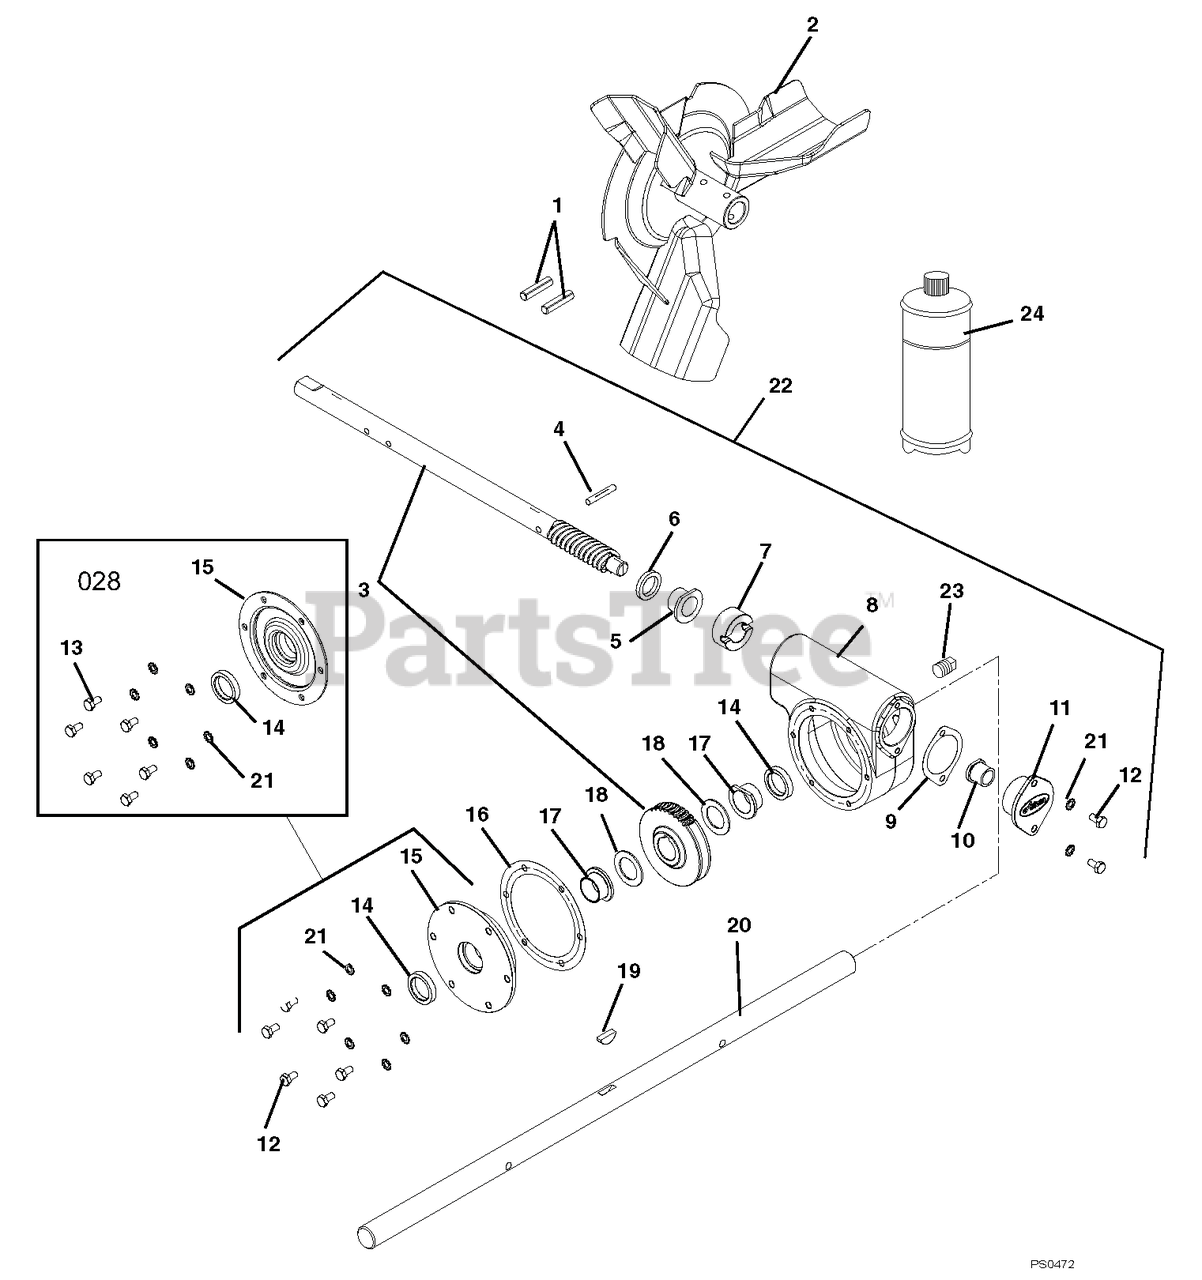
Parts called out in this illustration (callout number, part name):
1	PIN-ROLL .250X1.75
2	IMPELLER, 3 BLADE-14"
3	ASSY, WORM SHAFT & GEAR
4	PIN-GRV .250X1.50 TP E
5	BSHG-FLG .876 X 1.500 X .750
6	SEAL-OIL .875X1.25X.188
7	THRUST COLLAR, .875" ID
8	GEARCASE, CAST IRON-MACHINED
9	GASKET, FRONT - CAST IRON
10	BSHG-FLG .629 X 1.000 X .750
11	COVER, FRONT-CI GEARCASE
12	@BLT-HEX .25-20X.50 GR5 YWZC
13	BLT-HEX .25-20X.38 YWZC GR5
14	SEAL-OIL 1.000X1.375X.250
15	COVER, SIDE-CI GEARCASE
15	COVER, CI GEARCASE W/GASKET
16	GASKET, SIDE - CAST IRON
17	BSHG-FLG 1.003X1.5X.625
18	WSHR-HRD-THRS 1.007X1.542X.062
19	KEY-WDRF .25X.875 HRD #A
20	SHAFT, RAKE-26"
20	SHAFT, RAKE-28"
20	SHAFT, RAKE-32"
21	@WSHR-LK-EXT.262X.502X.026YWZC
22	GEAR CASE, CAST IRON-26"
22	GEAR CASE, CAST IRON-28"
22	GEAR CASE, 32" CAST IRON
23	PIPE PLUG, 1/4 NPT
24	ARIENS 16 OZ.BOTTLE OF L2 LUBE
